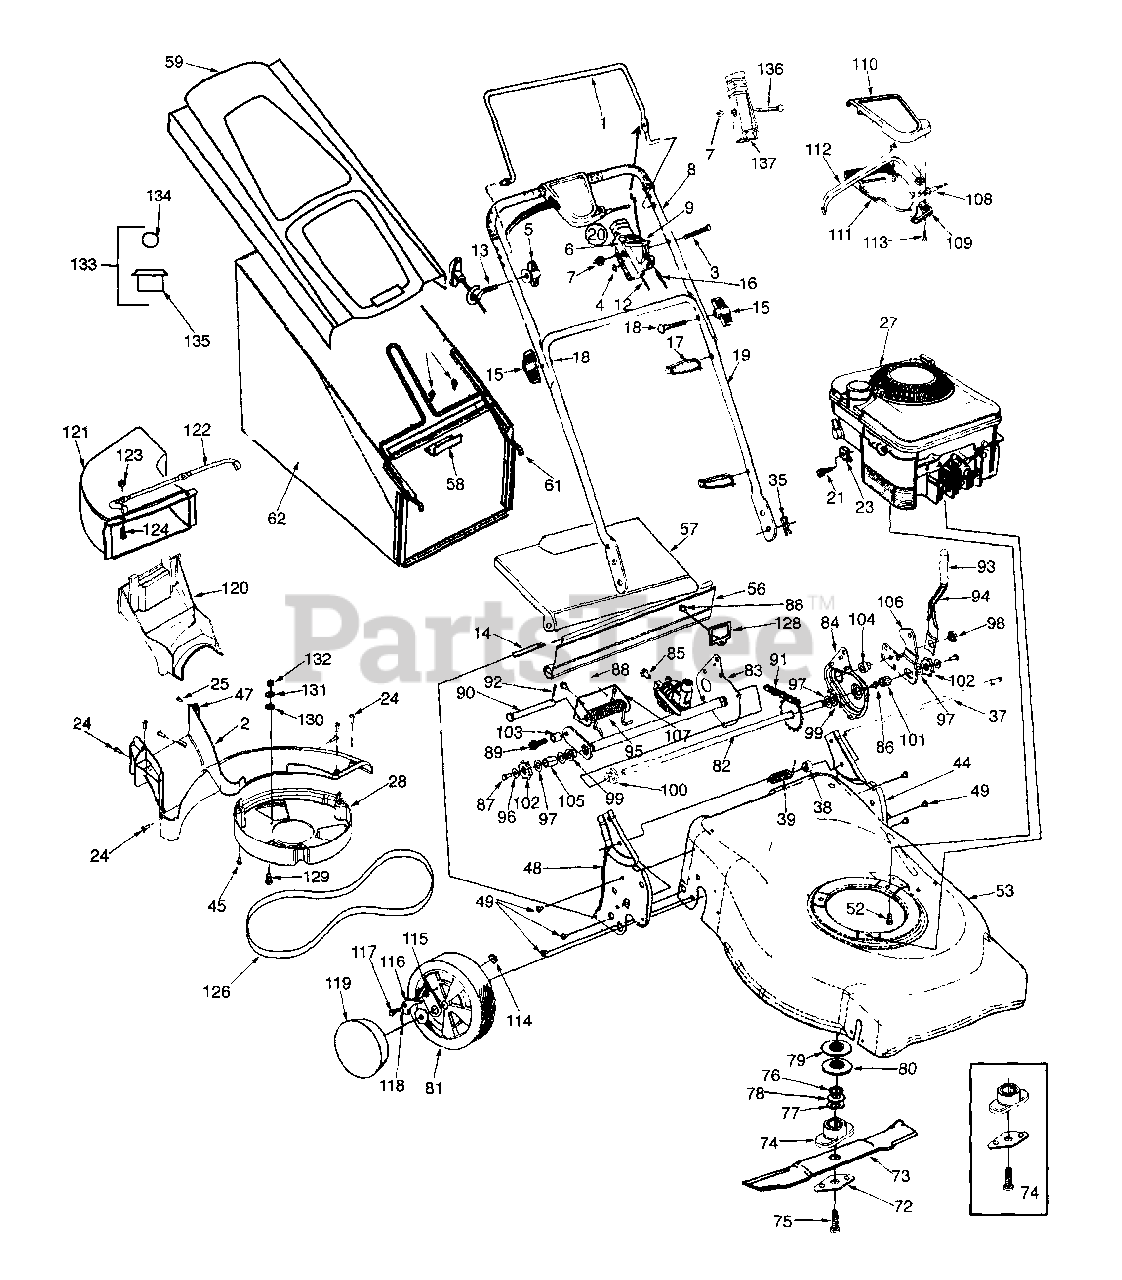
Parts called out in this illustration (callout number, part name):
2	Baffle
3	Oval C-Sunk Mach - Screw
4	Spring Washer .66" ID
5	Handle Knob 1/4-20 Thd.
6	Throttle Body
7	Hex L-Nut 1/4-20
9	Throttle Lever
12	Throttle Control Wire - 55"
13	Rope Guide
14	Wire-47" Lg.
15	Hand Knob
16	Control Cable-55"
17	Cable Tie
18	Cr.Hd. Bolt 5/16-18 x 2" Lg.
20	Throttle Ass'y Comp
21	Hex Self-Tap Scr. #10-32 x .62"
23	Cable Clamp
24	Screw H.L. 12-24
25	Screw Mach. B Tapp.
27	Engine
28	Belt Cover
35	Int. Cotter Pin 5/15" Dia.
37	Pivot Rod
38	Spacer .385 I.D.
39	Torsion Spring L.H.
47	U-Nut
52	Hex L-Wash. Hd. Scr. 3/8-16 x 1"
62	Grass Bag - Black
72	Blade Bell Support
73	21" Mulching Blade w/Star
74	Blade Adaptor Kit w/Star
75	Hex Bolt 3/8-24 x 2.5 Lg.
76	Spacer
77	Fl. Wash. .885 x 1.85 x .06
78	Spr. Wash. .890 x .7 x .04
79	Pulley Half - Upper
80	Pulley Half - Lower
81	Front Wheels 8" x 1.75"
82	Axle Assy: RR
86	Scr. TT 1/4-20
87	Hx Cap Screw 1/4-20
88	Hex Washer Screw 1/4-20 x .625
89	Scr 3/8 - 16 x 1.25
90	Pin - Clv. .500 Dia. x .4.62 Lg.
91	Chain: Endless 48:.500P x 22 Lg.
92	Pin-Cotter .125 O.D. x .75
93	Grip-Foam
94	Spring Lever
95	Torsion Spring
96	Bell Washer .265 x 75 x .062
97	Wash.Flat .508 I.D. x 1.0 O.D.:.020
98	Nut - Shoulder .625 x .165 Lg.
99	Bearing-Flg Hex
100	Bearing-Flg. Hex
101	Bearing-Sleeve
102	Ratchet Wheel
103	Spacer - .385 x .625 x .700
104	Spacer-Shld. .385 I.D. x .715 Lg.
105	Spacer Slv. .520 I.D. x .950 Lg.
109	Mounting Cap
110	Control Cover - Upper
111	Control Cover - Lower
112	Lever
113	Screw #10-16 x .625
114	Weld Top L. 1/4-20
115	Pawl Plate
117	Shldr. Scr. .340 x .285
118	Spring, Ratchet
119	Hub Cap, Gray (3-1/2" Dia.)
120	Mulch Plug
121	Chute Deflector
122	Chute Mounting Rod
123	Hex-L-Nut 1/4-20 thd.
124	Mach. Scr. 1/4-20
126	Belt
130	Lockwasher 1/4" Reg.
131	Fl. Wash. .271 x ..630 x .065
132	Nut 1/4-20
133	Flo Indicator Ass'y
134	Flo Indicator Ball
135	Flo Indicator Housing
136	Scr. 1/4-20:1.31 Lg.
137	Housing (w/o Throttle)
